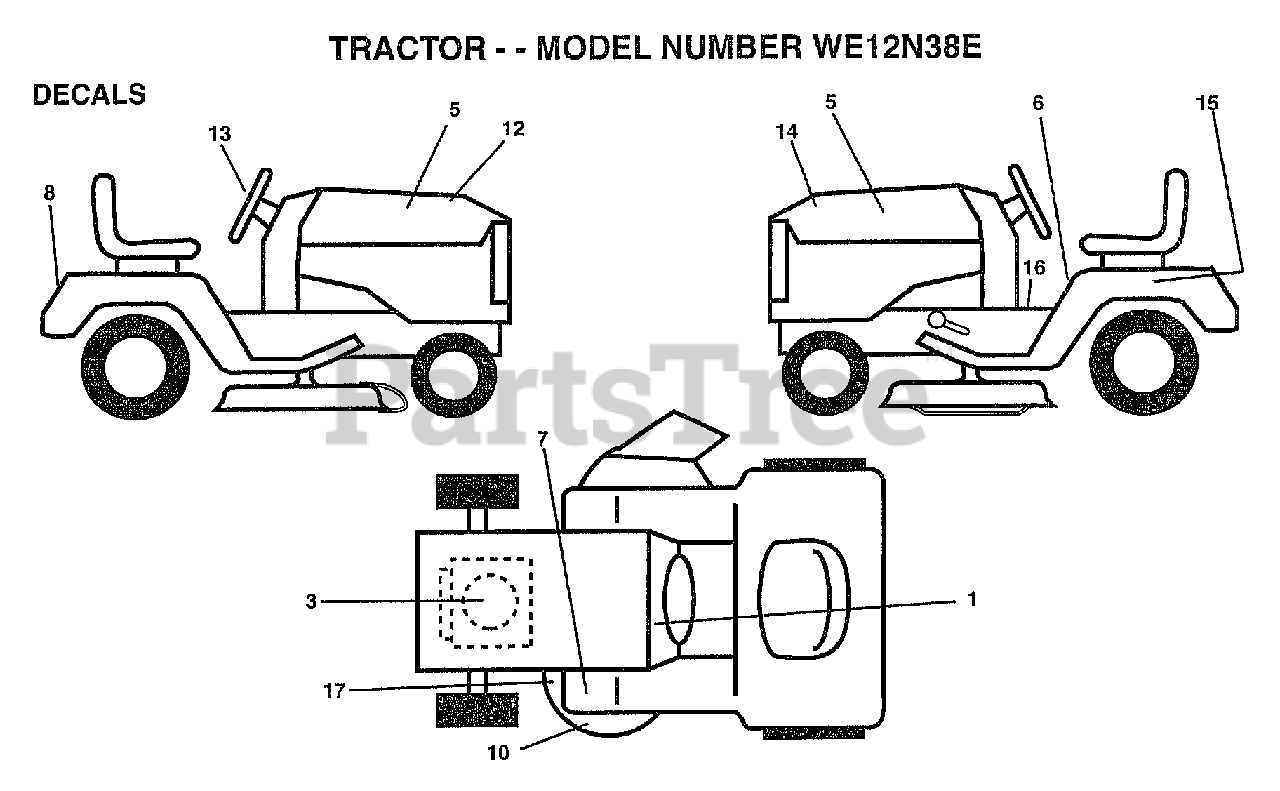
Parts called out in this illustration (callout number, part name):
1	"DECAL-OPER,GEAR D"
3	DECAL, HP ENGINE
5	DECAL PANEL SIDE
6	"DECAL DANGER,FEND"
8	DECAL-FENDER
12	"DECAL HOOD, RH"
13	DECAL INS STEER W
14	"DECAL HOOD, LH"
15	DECAL.BATRY.3-3908
16	DECAL BRAK PARK
17	DECAL
